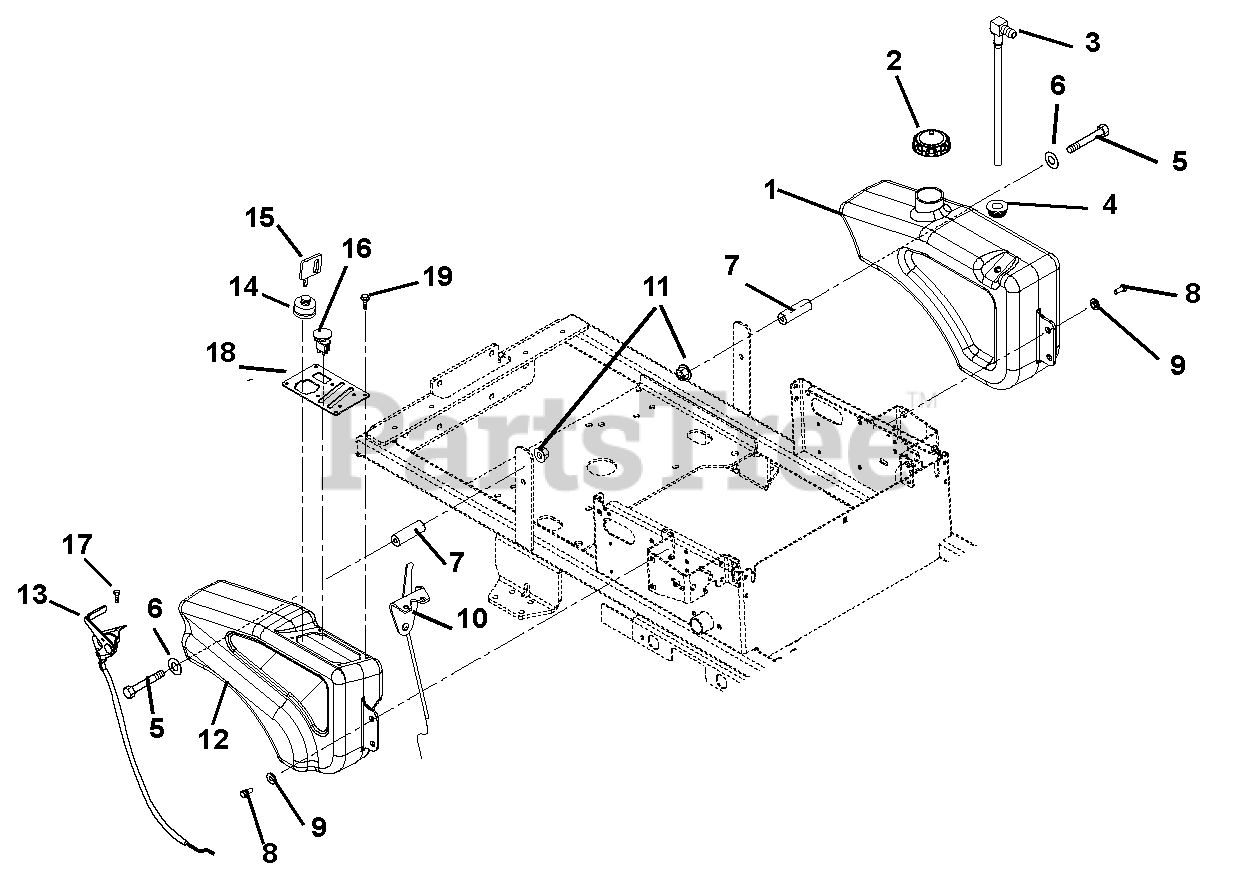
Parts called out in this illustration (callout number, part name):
1	Gas Tank
2	Fuel Cap
3	Fitting, Tank
4	Bushing, Flange .375 x 1.062 x .625
5	Bolt, Hex .31-18 x 3.50 Grade 5
6	Washer, Flat-Steel .38 x .875 x .083
7	Spacer, Tank Mount
8	Bolt, Hex .31-18 x .75 Grade 5
9	Shoulder Spacer
10	Cable, Choke Cable (404)
11	Nut, .31-18 Nyloc Flange
13	Cable, Throttle (404)
14	Key Switch
15	Key, w/cap
16	Switch, Clutch
17	Screw, Tapping 10-24 x .50 Hex Washer Head (404)
18	Control Panel (404)
19	Rivet, Plastic .195 Diameter
